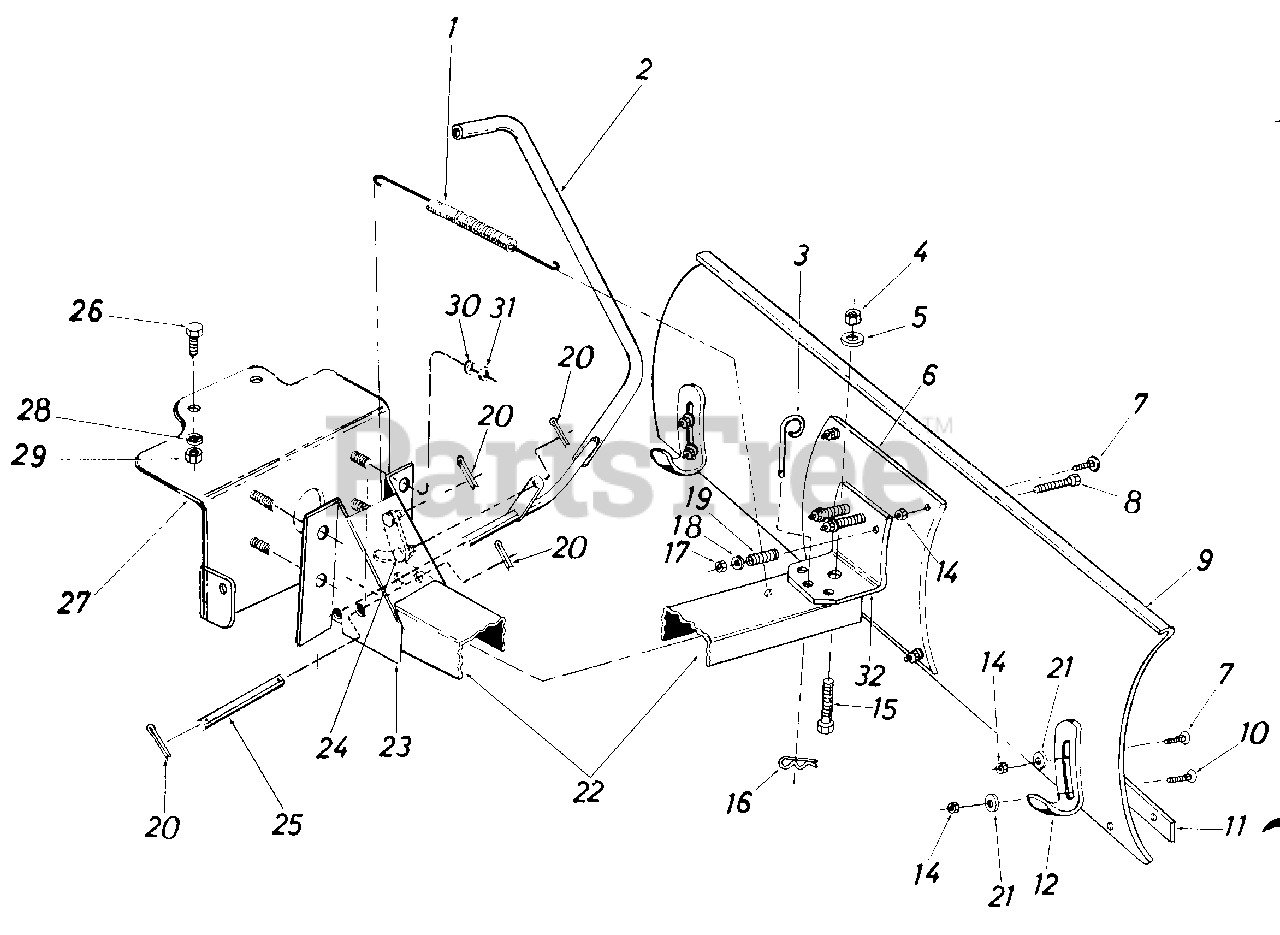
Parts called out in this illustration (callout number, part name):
1	Extension Spring
2	Lift Handle Ass'y.
3	Pivot Lock Pin
4	Hex Cent. L.Nut 1/2-13 Thd.
5	Fl.Wash. 17/32 I.D. x 1.25" Lg.
6	Reinforcement Plate
7	Carriage Bolt 5/16-18 x .75" Lg.*
8	Hex Scr. 3/8-16 x 3.75" Lg.(Grade 5)
9	42" Blade
10	Carriage Bolt 5/16-18 x 1.00" Lg.*
11	42" Wear Plate
12	Shoe Skid
14	Hex Cent. L.-N ut 5/16-18 Thd . *
15	Hex Scr. 1/2-13 x 1.25" Lg.*
16	Hair Pin Coter
17	HexCent. L.Nut3/8-16Thd.
18	Fl.Wash. 3/8" I.D.
19	Compression Spring
20	Coter Pin 1/8" Dia. x 1.00" Lg.*
21	Fl.Wash. 5/16" I.D.
22	Push Bar Channel
23	Pivot Support Bracket
24	Lift Link
25	Channel Pivot Shaft
26	Hex Scr. 3/8-16 x 1.00" Lg.(Grade 5)
27	Support Bracket Ass'y.
28	L.Wash. 3/8 I.D.*
29	Hex Nut 3/8-16Thd.*
30	L.Wash. 3/8" I.D.*
31	Hex Jam Nut 3/8-16 Thd.
32	Support Bracket
